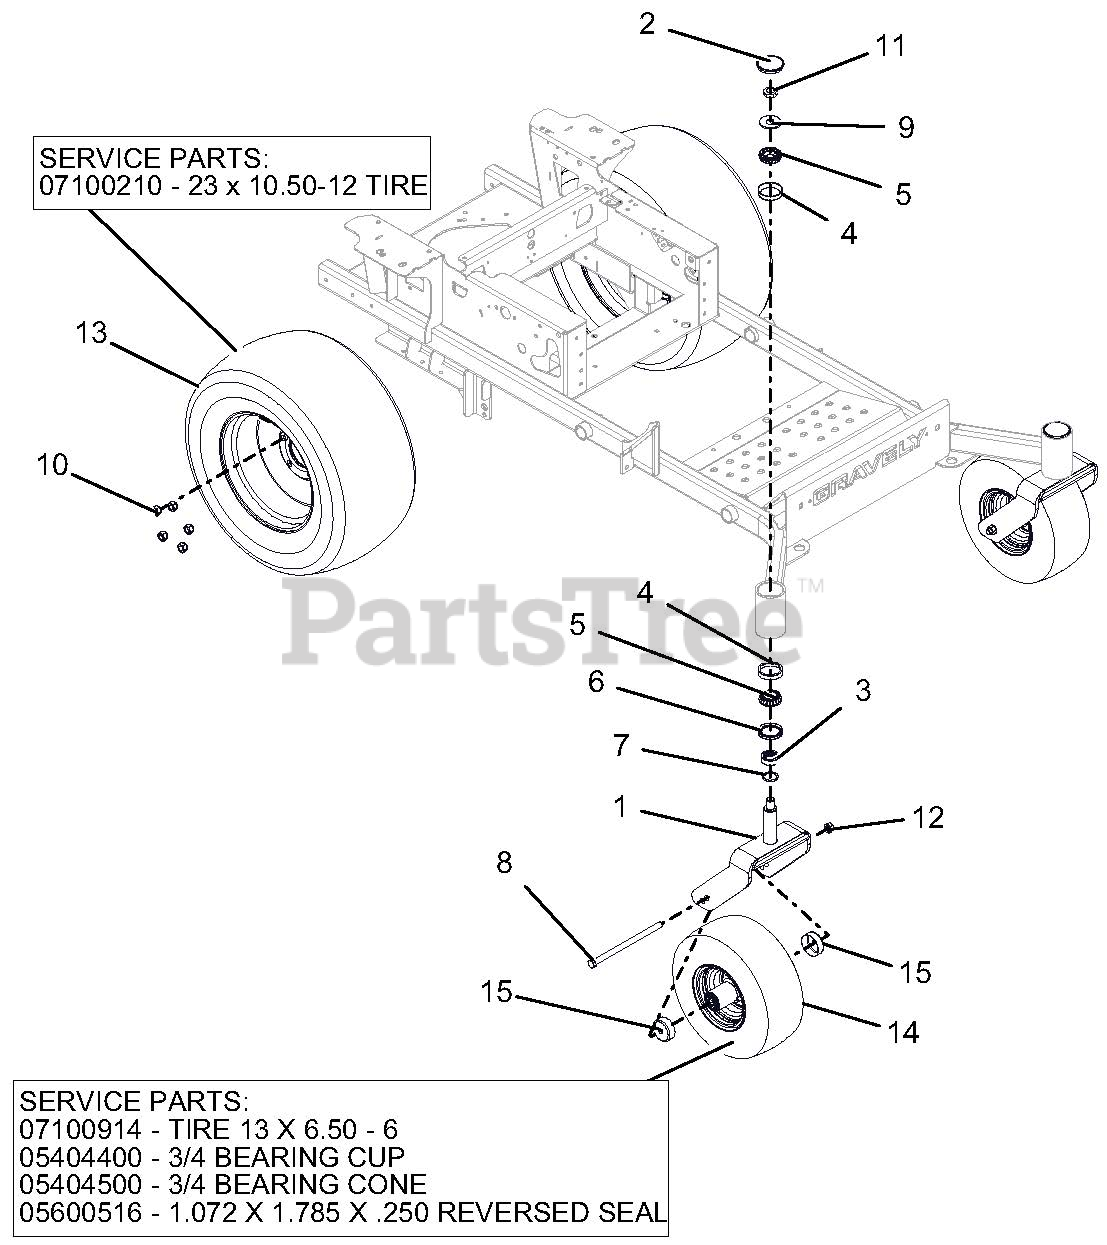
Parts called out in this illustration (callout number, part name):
1	WMT, CASTER FORK - RED
2	CAP, DUST
3	SPCR, FRONT CASTER FORK
4	BRG, CUP 2.328 X .465
5	BRG, CONE 1.250 X .660
6	SEAL, OIL 1.75 X 2.332 X .312
7	O-RING, .139 W X 1.234 ID
8	BLT-HEX .50-13X9.00 GR5 YWZC
9	WSHR-FL-STL.812X2.00X.148YWZC
10	NUT, LUG .500-13
11	@NUT-LK-CTR-JAM .75-16 YWZC
12	NUT, LK-TOP-FLG .50-13 YWZC
13	ASSM TIREWHEEL, 23X10.5-12
13	23 X 10.00-12 TIRE
14	TIRE/WHEEL, 13 X 6.50-6 SMOOTH
14	TIRE 13 X 6.50-6
14	3/4 BEARING CUP
14	3/4 BEARING CONE
14	1.072 X 1.785 X .250 REVERSED SEAL
15	SHIELD, WHEEL BEARING
